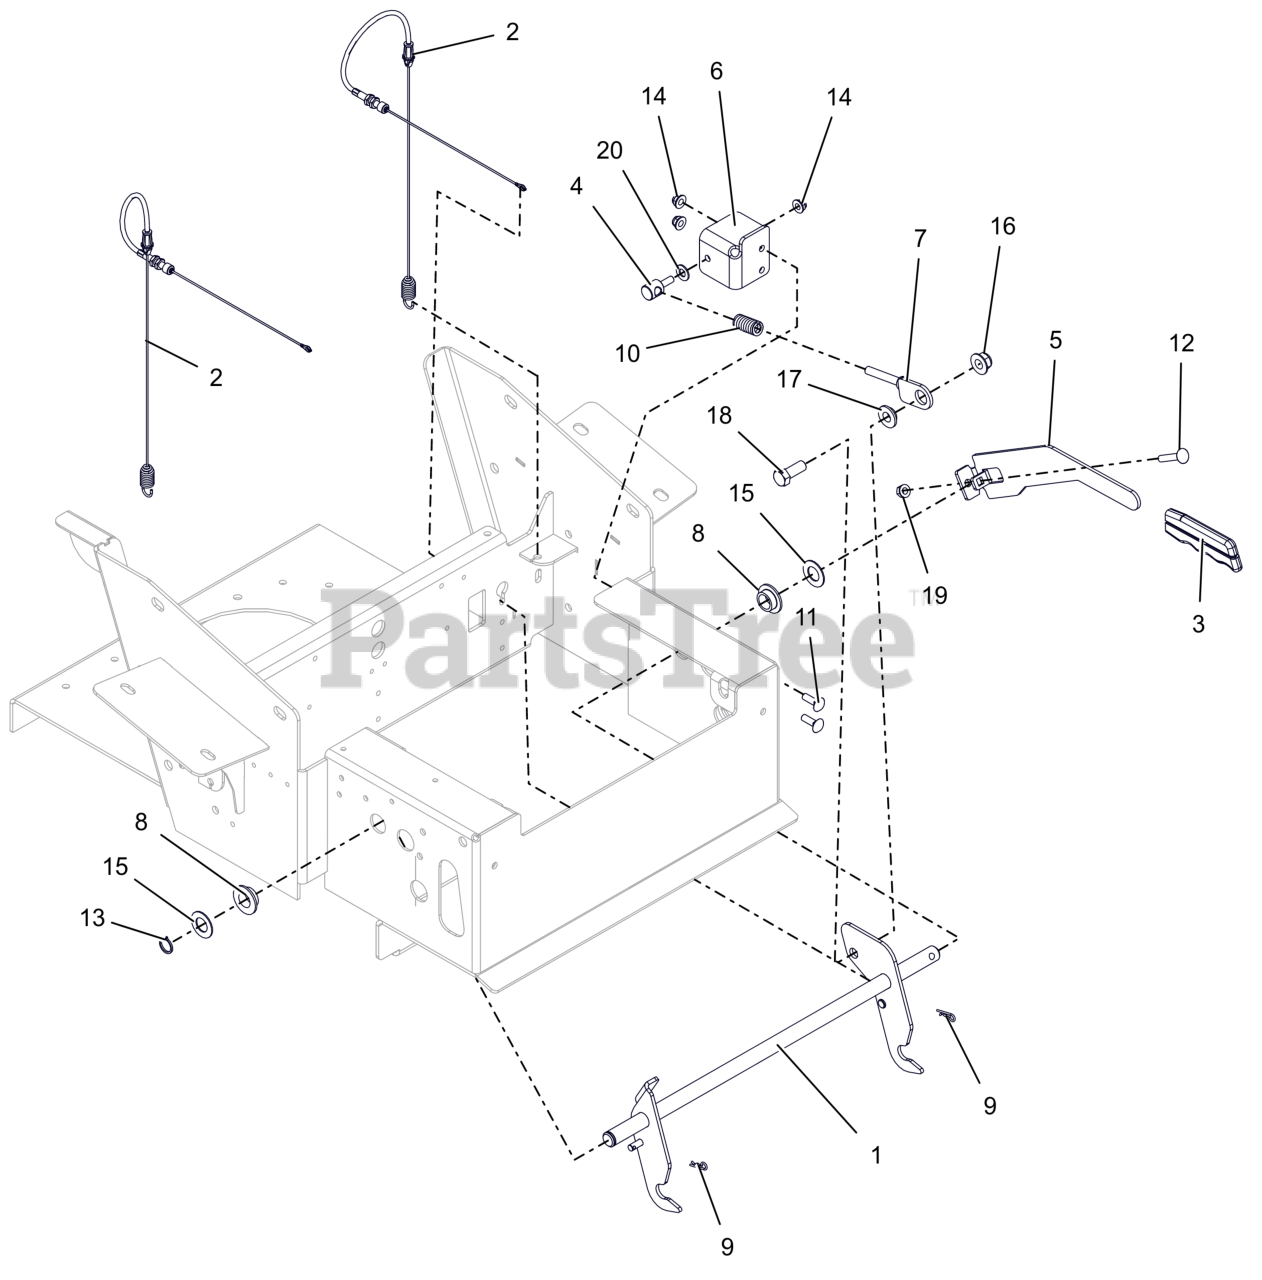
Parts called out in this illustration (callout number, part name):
1	PT/PT100 BRAKE LEVER WMT-LOW F
2	CABLE, BRAKE ACCUATING
3	GRIP, PARKING BRAKE (YELLOW)
4	.38-16 TRUNNION - LOW FILM
5	PT/PT100 BRAKE HANDLE - BLK
6	TRUNNION MTG BRACKET - BLACK
7	WLDMT, BRAKE SPRING MOUNTING
8	BSHG-FLG .762X1.48X.44 NYL
9	PIN, HAIR #213 .08X1.19 ZCC
10	SG-COMP .142 X .710 X 1.75
11	BLT,RHSN .31-18X1.00 G5 ZCC
12	BLT, RHSN .31-18X1.75 G5 ZCC
13	RG-RTNG-EXT .689X.078
14	NUT,NYL-FLG .31-18 GF ZCC
15	WSHR, FLT .755X1.375X.062 ZCC
16	NUT,NYL-FLG .50-13 GF ZCC
17	BSHG-FLG .515X.750X.310X1.120
18	BLT,HEX .50-13X1.25 G5 ZCC
19	NUT,LK-CTR-FLG .31-18 GF ZCC
20	WSHR,FLT .406X.812X.065 ZCC
